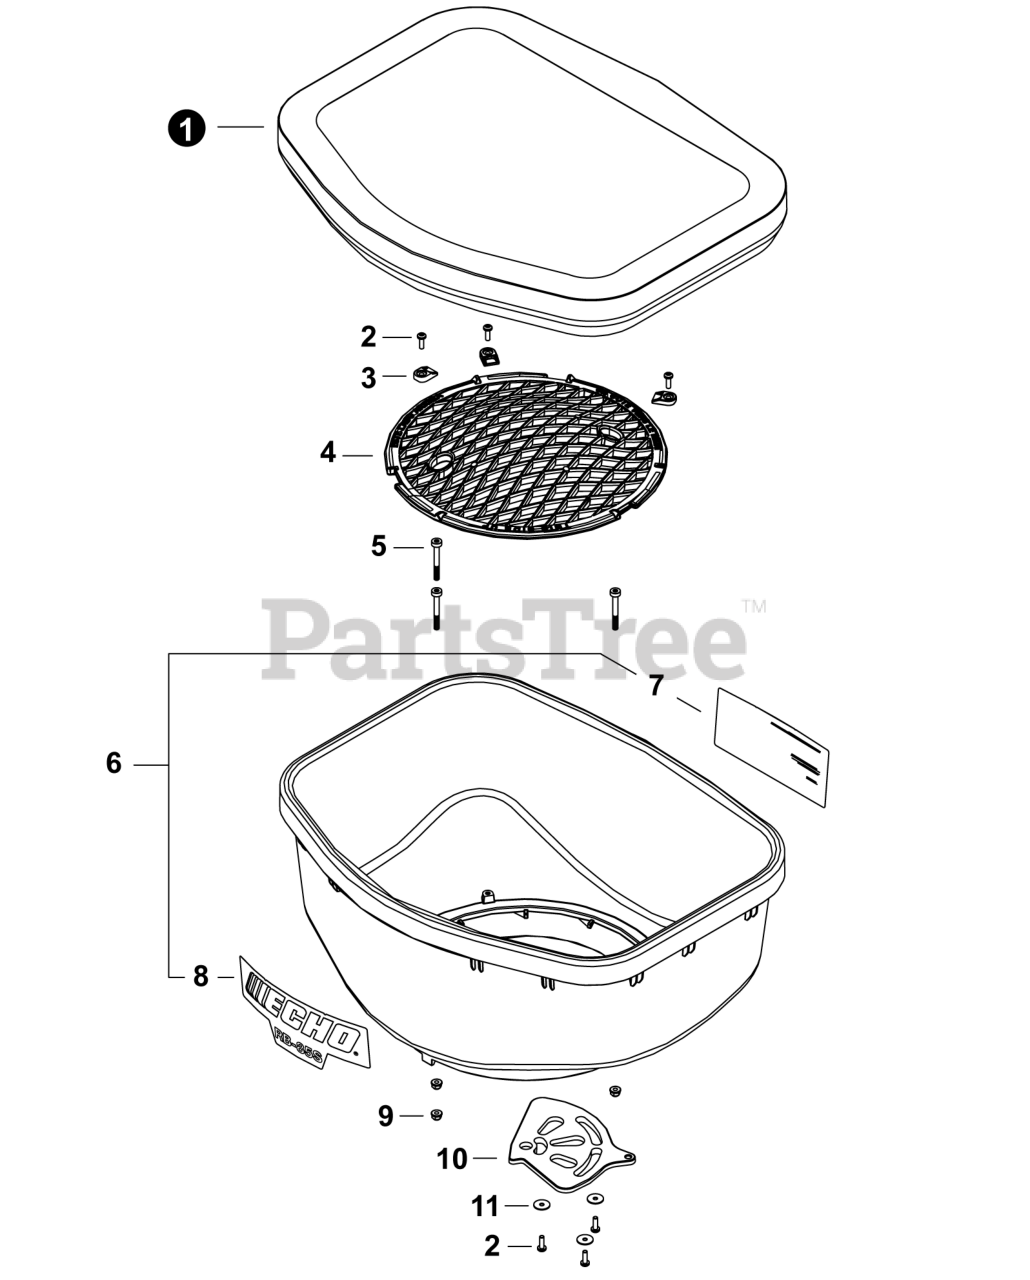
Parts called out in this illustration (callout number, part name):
1	COVER, HOPPER
2	SCREW, TAPPING 5x16
3	CLIPS, SCREEN
4	SCREEN, HOPPER
5	BOLT, M6 X 50MM
6	HOPPER ASSY
7	LABEL - OPERATION
8	LABEL - RB-85S
10	PLATE, REGULATOR
11	WASHER 5 MM
